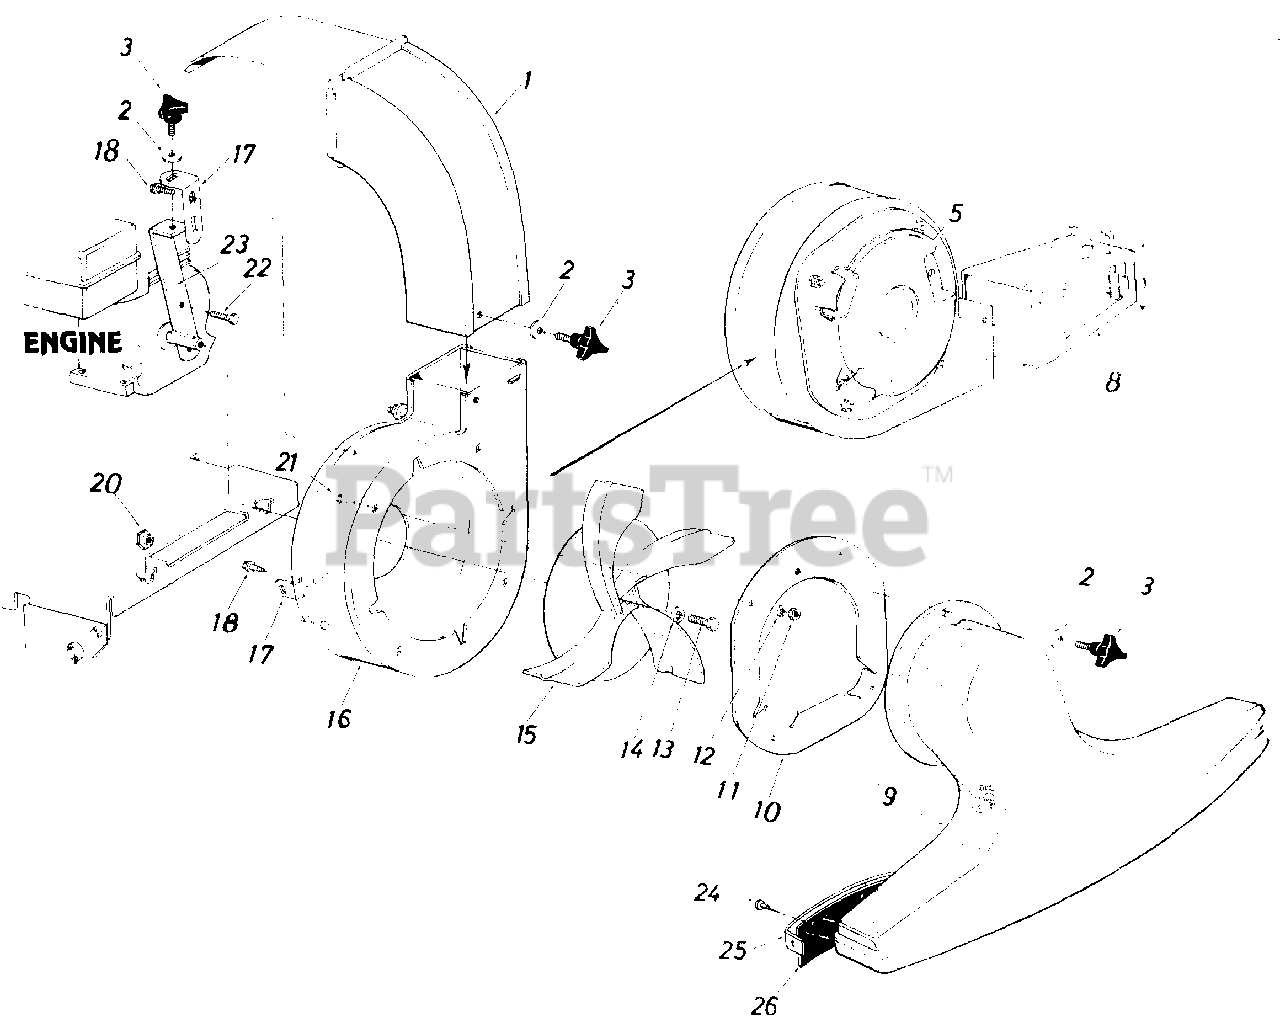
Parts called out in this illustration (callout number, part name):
3	3-Arm Thumb Scr. 5/16-18 x .75" Lg.
5	Blower Guard
10	Nozzle Plate Ass'y.
11	Hex Nut 5/16-18 Thd.
12	L.-Wash. 5/16" I.D.
13	Hex Bolt 3/8-24 x 1.25" Lg.
14	L.-Wash. 3/8" I.D. H.D.
15	Air Vane Plate Ass'y. w/pulley
16	Blower Housing Complete
20	Hex Shoulder Nut .50 I.D.
21	Carriage Bolt 5/16-18 x .62" Lg.
22	Hex Locking Bolt 5/16-24 x .75" Lg.
